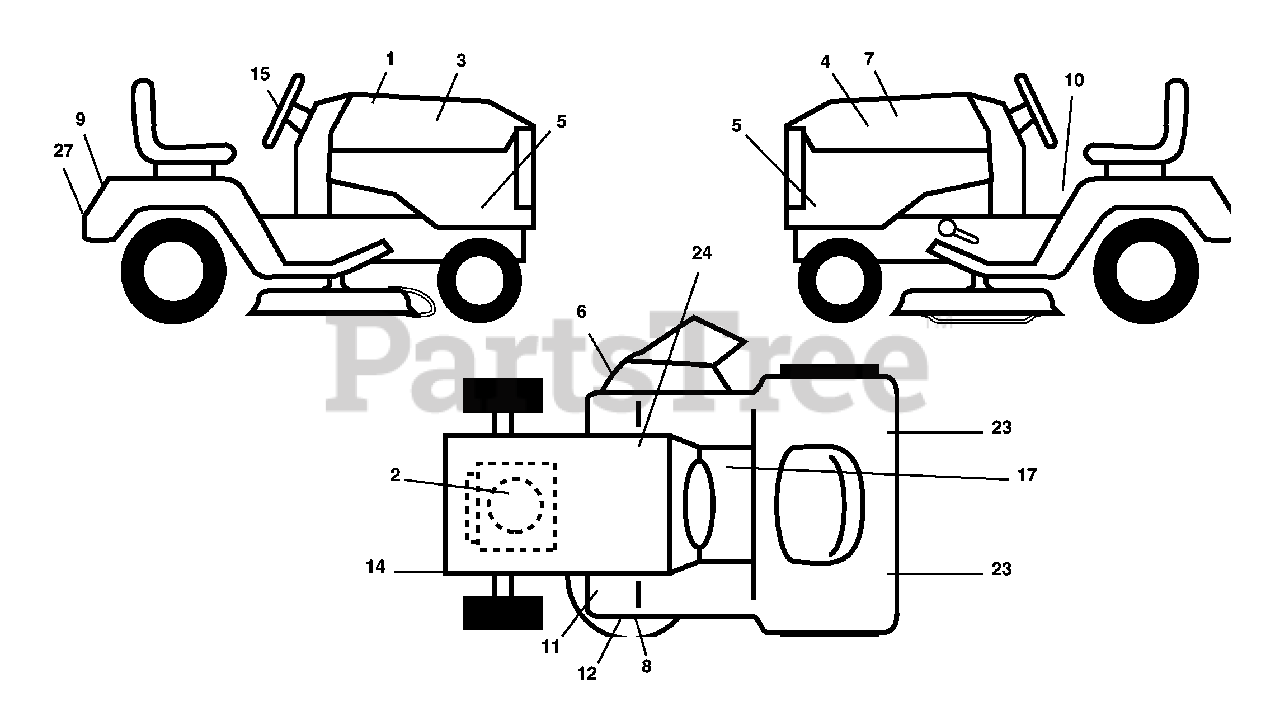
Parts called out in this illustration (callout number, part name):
1	Decal, Final
2	Decal, Engine
3	Decal, Hood, RH
4	Decal, Hood, LH
5	Decal, Side Panel
6	Decal, Warning
7	Decal, Hood Cust. Resp.
8	Decal, Mower Heavy Duty
9	Decal, Fender
10	Decal, Danger
11	Decal, Foot Rest
12	Decal, Deck Caution
14	Decal, V-Belt Schematic
15	Decal, Ins. Strg Whl
17	Decal, Saddle Oper.
23	Reflector, Taillight
24	Decal, Btry Dngr/Psn
27	Decal, Drawbar
